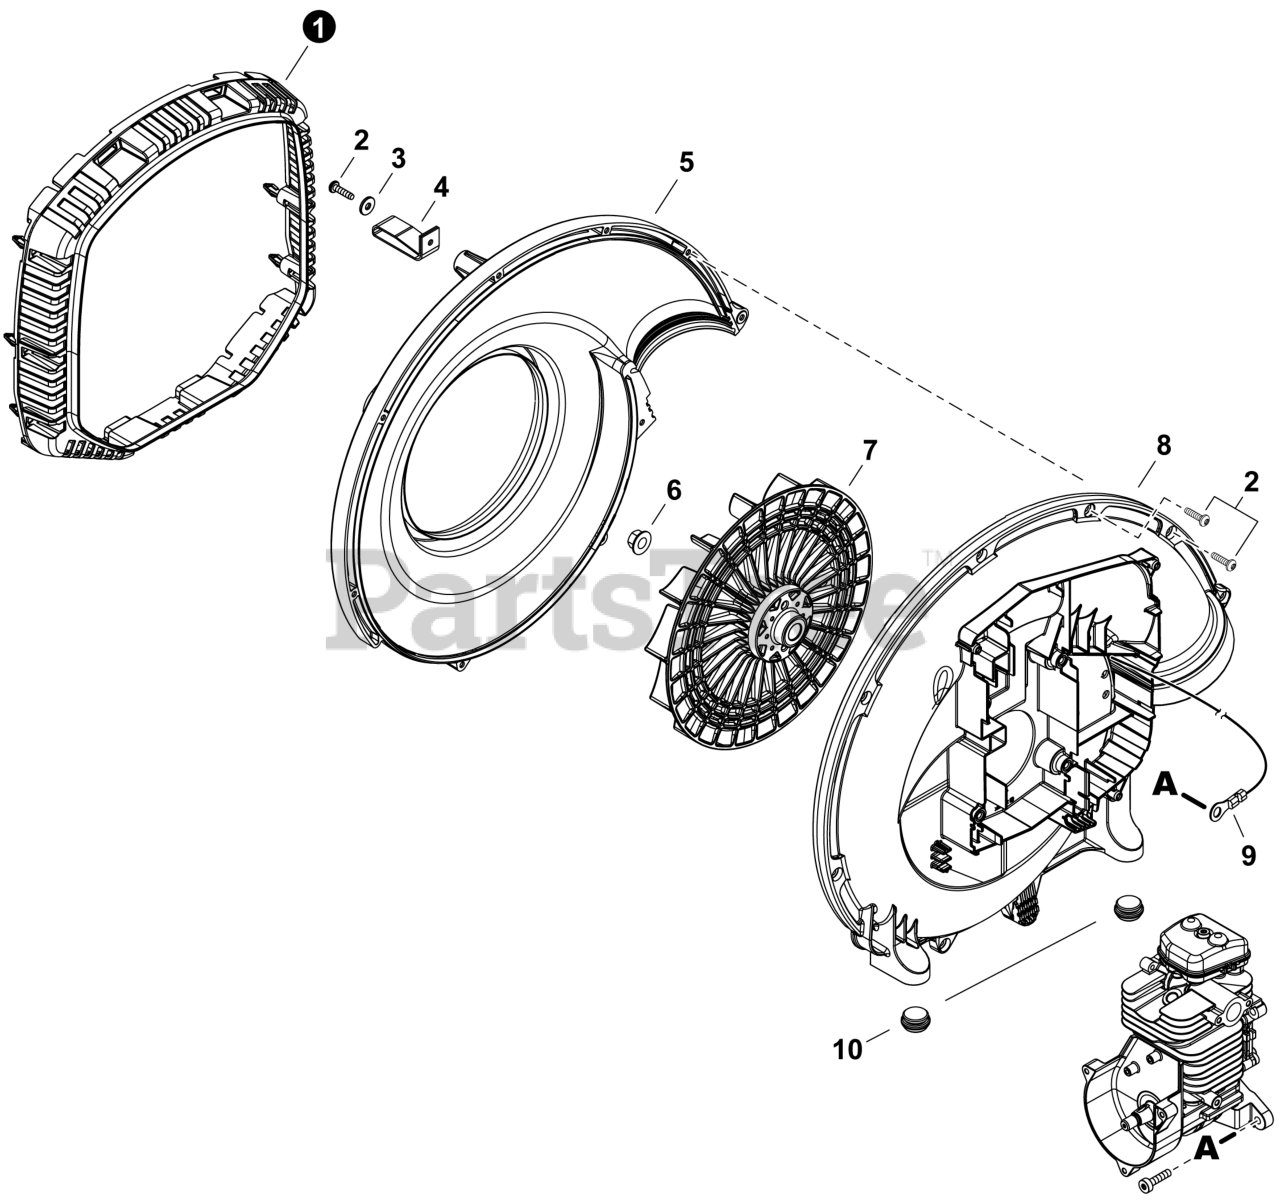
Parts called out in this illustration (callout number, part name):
1	GUARD, DEBRIS
2	BOLT, TORX 5x20
3	WASHER 5.5x16x2T
4	STRAP, SAFETY
5	COVER, FAN
6	NUT, FLANGE 10x1.25
7	FAN, BLOWER
8	CASE, FAN
9	WIRE, ANTI-STATIC
10	CUSHION
